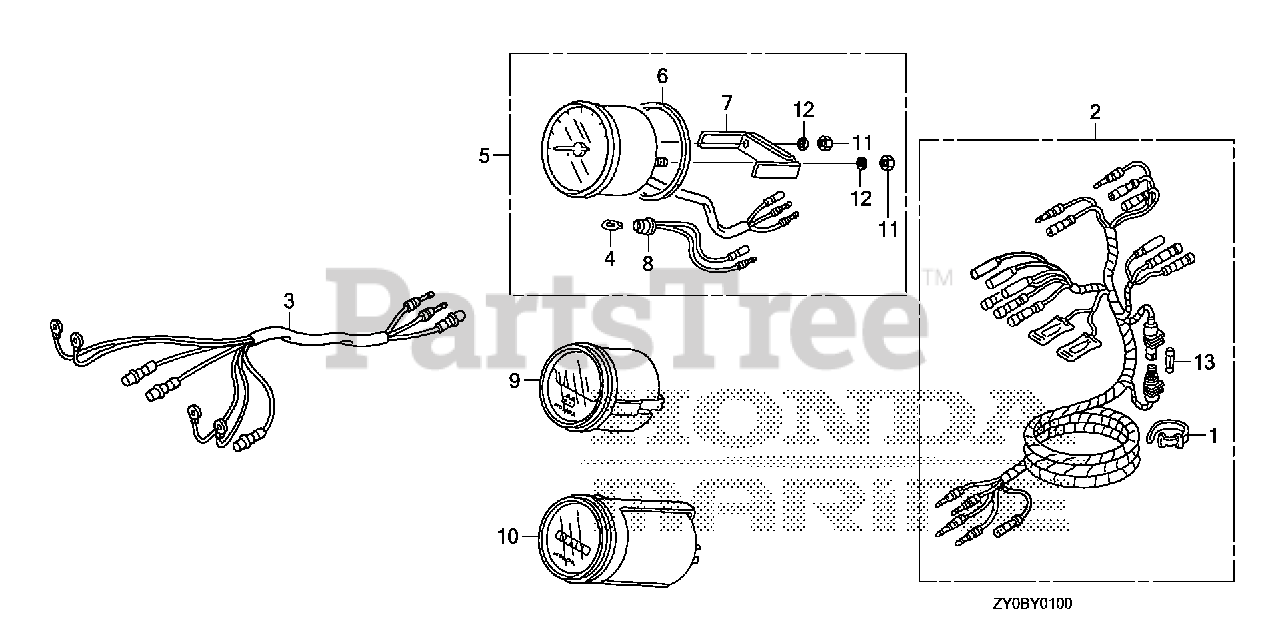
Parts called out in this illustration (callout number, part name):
1	BAND B1, CABLE Use up to Frame SN 1001879.
2	HARNESS ASSY., METER (A)
3	HARNESS ASSY., METER (B)
4	BULB, WEDGE BASE (T10) (12V 1.7W) (STANLEY)
5	TACHOMETER ASSY.
6	GASKET
7	BRACKET (TO 1015209) (FROM 1015210)
8	SOCKET (TO 1015209) (FROM 1015210)
9	METER ASSY., VOLT
10	METER ASSY., HOUR L.C.D.
11	NUT, HEX. (5MM)
12	WASHER, SPRING (5MM)
13	FUSE A (10A)
